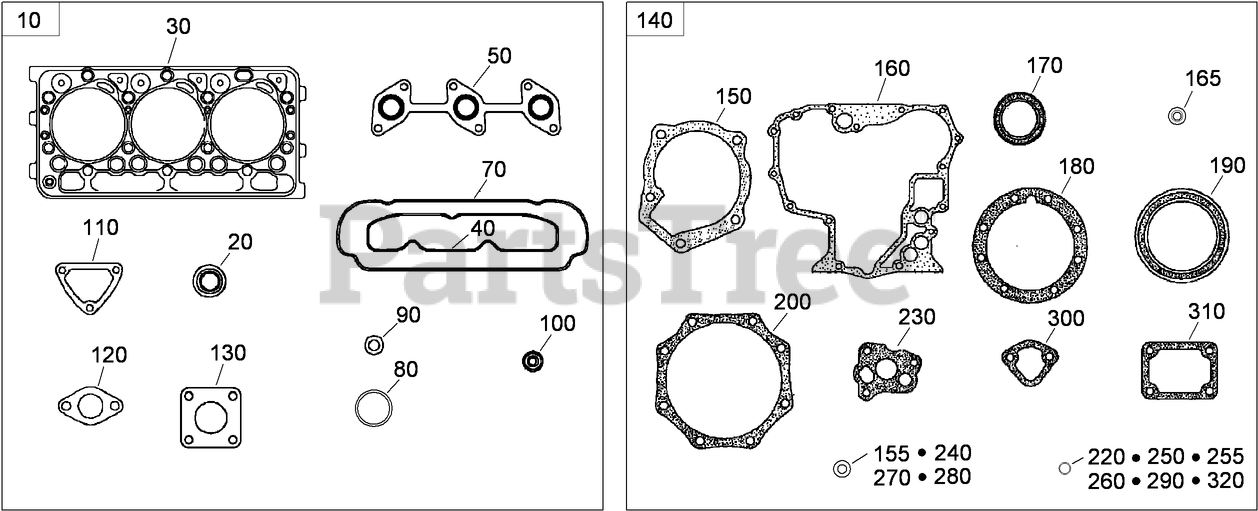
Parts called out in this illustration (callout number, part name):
10	UPPER GASKET KIT
20	SEAL-STEM, VALVE
30	GASKET-HEAD, CYLINDER
40	GASKET-MANIFOLD, INTAKE
50	GASKET-MANIFOLD, EXHAUST
70	GASKET-COVER, HEAD
80	O-RING
90	GASKET
100	SEAL-HEAT
110	GASKET-FLANGE, WATER
120	GASKET-THERMOSTAT
130	GASKET-MUFFLER
140	LOWER GASKET KIT
150	GASKET-PUMP, WATER
155	GASKET
160	GASKET-CASE, GEAR
165	WASHER
170	SEAL-OIL
180	GASKET-CASE, BEARING
190	SEAL-OIL
200	GASKET-COVER, CASE
220	O-RING
230	GASKET-PUMP, OIL
240	GASKET
250	O-RING
255	O-RING
260	O-RING
270	GASKET
280	GASKET-PAN, OIL
290	O-RING
300	GASKET-PUMP, FUEL
310	GASKET-PLATE, CONTROL
320	O-RING
